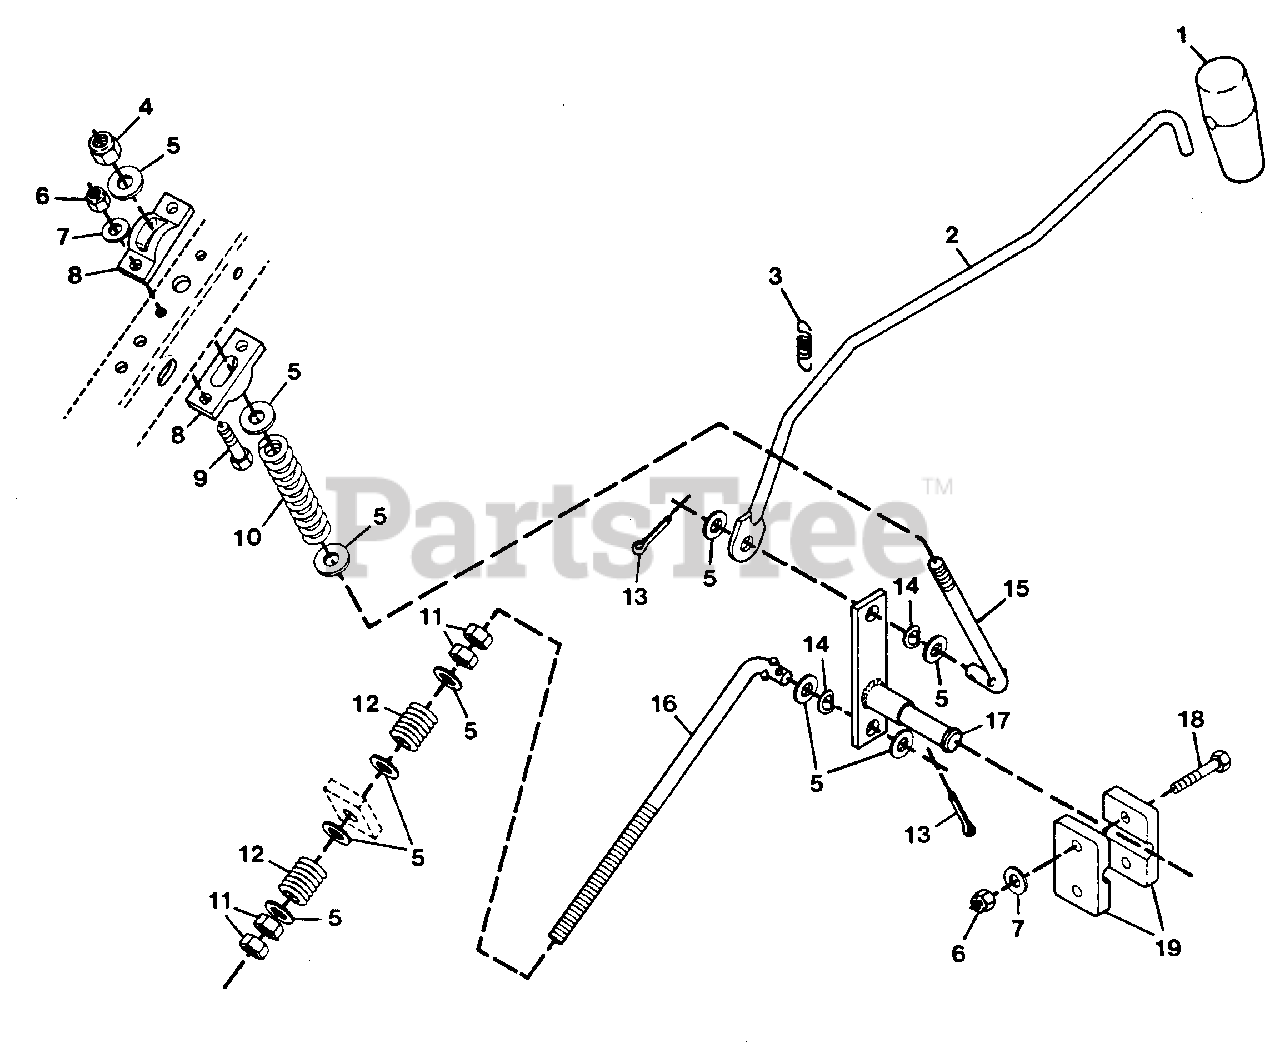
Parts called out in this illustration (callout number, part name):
1	HANDLE, RUBBER SHIFTER
2	ROD, SHIFTER
3	SPRING, EXTENSION .50X1.25
4	NUT, LOCK 3/8-16
5	WASHER, FLAT .406X.812X.065
6	NUT, LOCK 1/4-20
7	WASHER, FLAT .281X.625X.065
8	CAM, SHIFTER
9	BOLT, HEX 1/4-20X1.00
10	SPRING, COMP. .720X2.75
11	NUT, JAM 3/8-16 HEX
12	SPRING, COMP. 1X.78X338
13	PIN, COTTER .125X.750
14	WASHER, SPRING .375 I.D.
15	LINK, SHIFTER STOP
16	LINK, SHIFTER
17	WELDMENT, SHIFTER CRANK
18	BOLT, HEX 1/4-20X1.50
19	BLOCK, SHIFT LEVER
